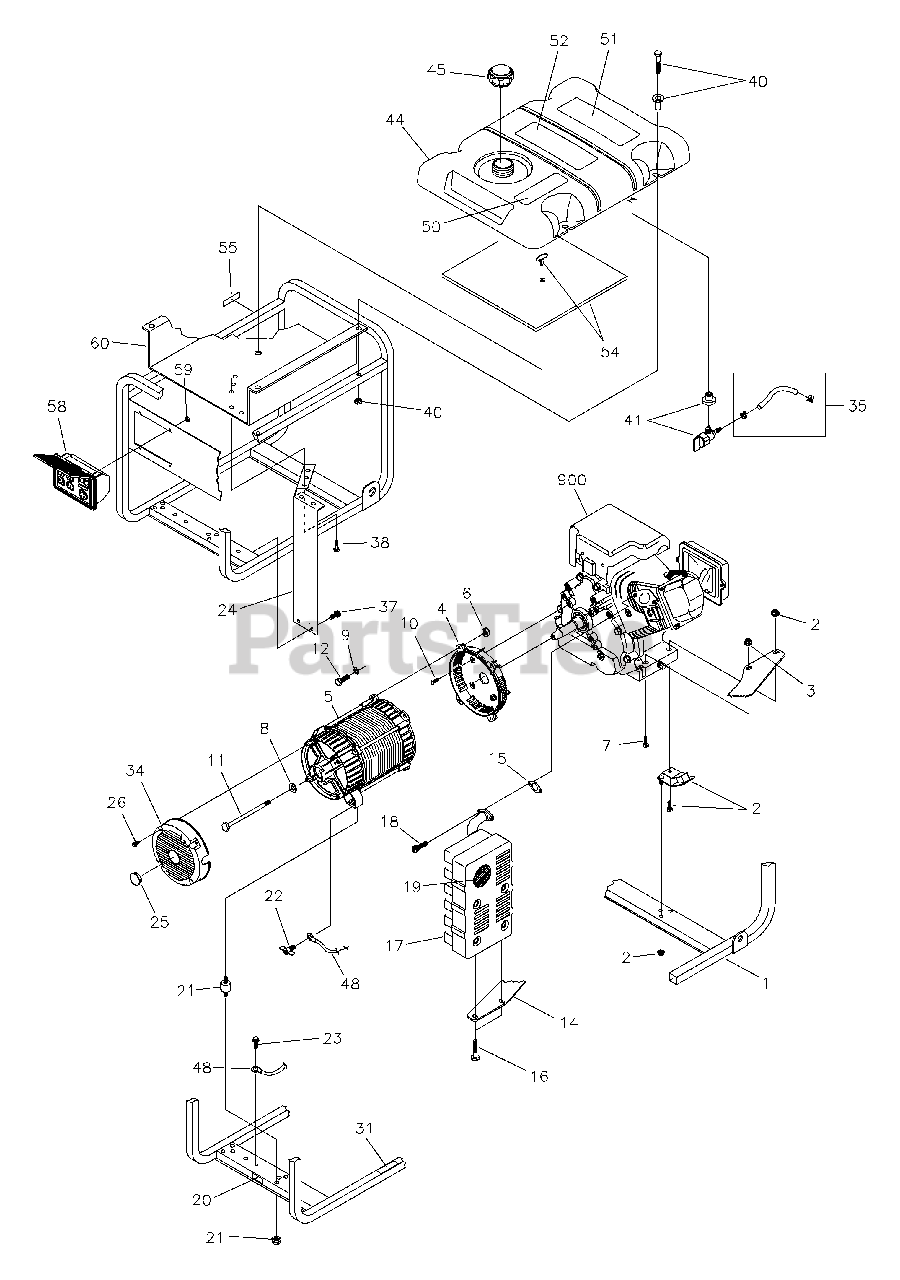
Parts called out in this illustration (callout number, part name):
2	KIT, Vibration Mount 45°
3	NUT, M8 Flange Serrated
4	HOUSING, Engine Adapter
5	ASSY,Alternator
8	WASHER, M8 Flat
9	WASHER, M8 Lock
10	SBHCS, 3/8-16 x 1.0 Lg.
11	HHCS, 5/16-24 x 7
14	BRACKET, Muffler
15	GASKET, Exhaust
18	SCREW, 5/16 - 18 x 3/4"
19	SCREEN, Spark Arrest
20	DECAL, Ground, Green
21	KIT,Vibration Mount
22	SCREW,Wing M6 1.0 x 16
23	SCREW, 10-16 x 3/4 Self Drill
24	SHIELD, Heat
26	SCREW, M5-0.8 x 10,Taptite
31	DECAL, Hot Muffler
34	COVER, Bearing Carrier with Cap
35	KIT, Fuel Hose w/ Clamps
37	SCREW, 12-14 x 7/8 Self Drilling
38	SCREW, 10-24 x 1/2 Crimptite
40	KIT, Fuel Tank Hardware
41	KIT,Valve,Tank
44	ASSY,Tank, Fuel
45	CAP, Fuel
48	WIRE, Ground
50	DECAL, Gas Fill
51	DECAL, Danger
52	DECAL, Start Instructions
54	KIT, Insulation w/ Clip
55	DECAL, Fuel Shut-off
58	ASSY, Control Panel
60	SHIELD, Heat
900	ENGINE
